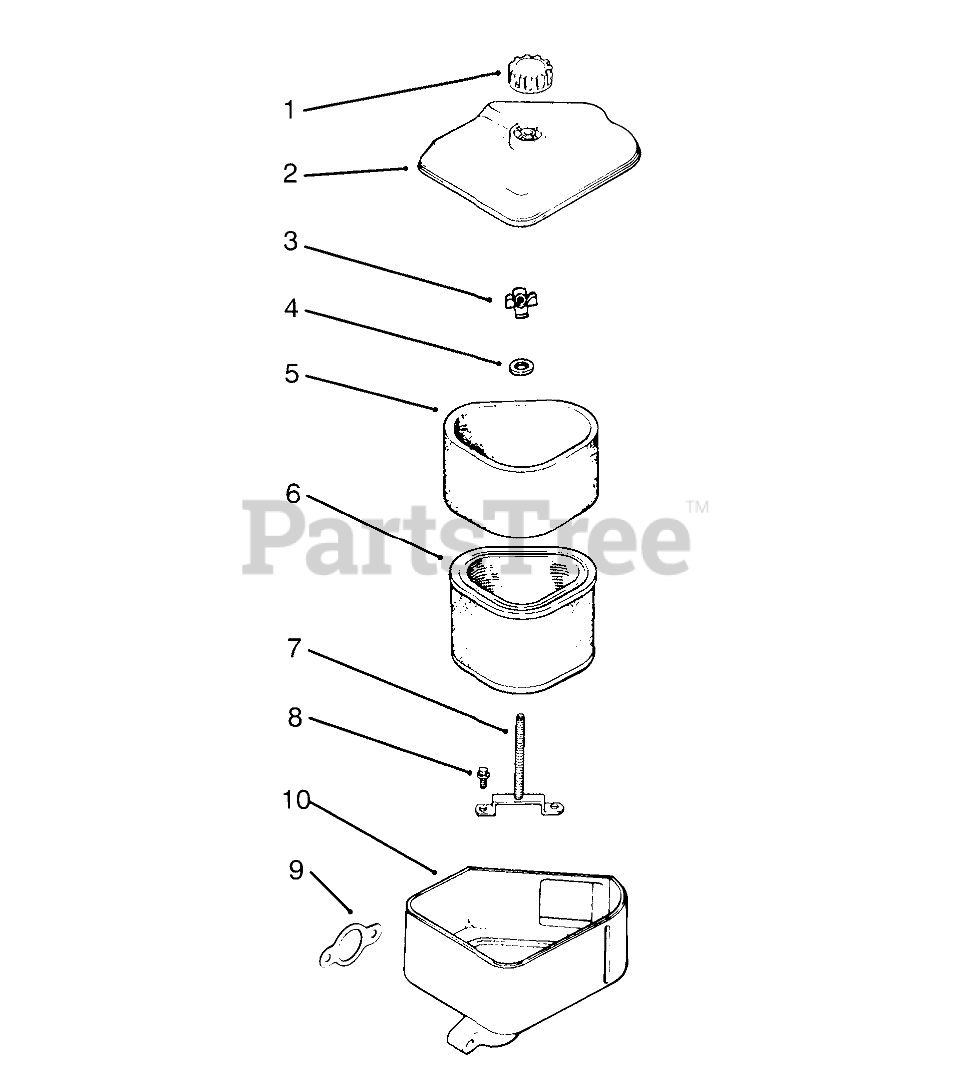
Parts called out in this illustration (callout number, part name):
1	Knob-Air Cleaner Cover (Only On: 72042,72043,72062,72063)
2	Cover-Air Cleaner (Only On: 72042,72043,72062,72063)
3	Nut-Wing (Only On: 72042,72043,72062,72063)
4	Washer-Flat (Only On: 72042,72043,72062,72063)
5	Element-Air Cleaner (Only On: 72042,72043,72062,72063)
6	Precleaner-Element (Only On: 72042,72043,72062,72063)
7	Stud-Mounting Plate (Only On: 72042,72043,72062,72063)
8	Screw-Mounting Plate (Only On: 72042,72043,72062,72063)
9	Gasket-Air Cleaner (Only On: 72042,72043,72062,72063)
10	Base-Air Cleaner (Only On: 72042,72043,72062,72063)
